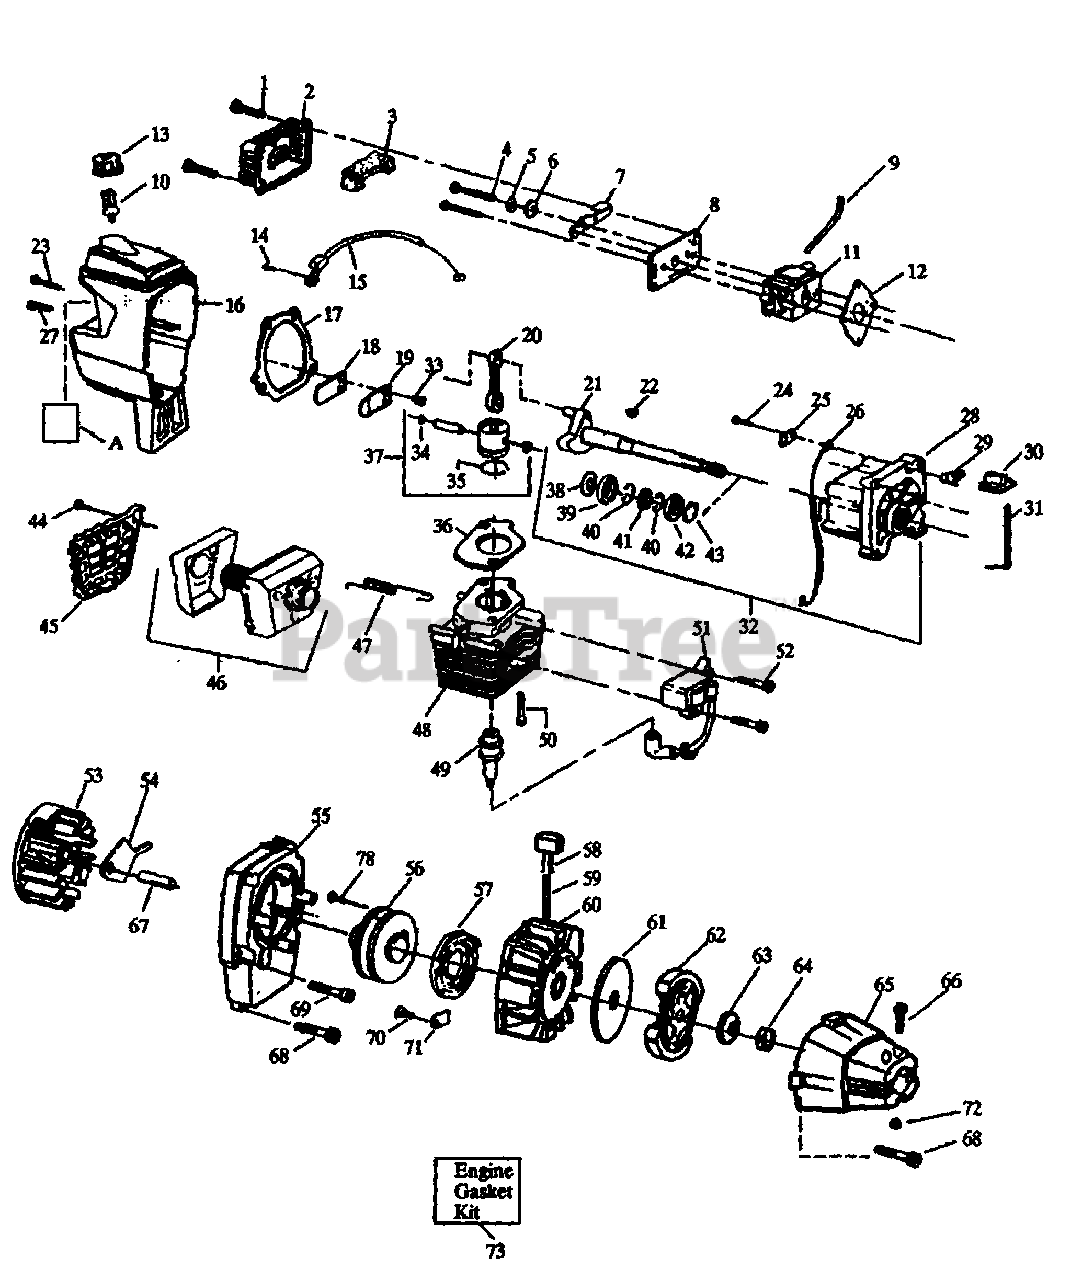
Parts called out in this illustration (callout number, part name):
2	Air Filter Cover
3	Air Filter
5	Spacer
6	Wave Washer
7	Choke Shutter
8	Air Filter Plate
9	Fuel Line 10t
10	Fuel Pick-up Ass'y.
11	Carburetor (WA-199)
12	Carburetor Gasket
13	Fuel Cap Ass'y.
15	Throttle Cable Ass'y.
16	Shroud & Tank Ass'y
17	Crankcase/Shroud Gasket
20	Connecting Rod Ass'y
21	Crankshaft Ass'y.
22	Flywheel Key
25	Kill Switch Insulator
28	Crankcase Ass'y.
29	Kill Switch Ramp
30	Kill Switch Button
31	Kill Switch Spring
32	Crankcase & Crankshaft Ass'y (#21, 28, 38 & 43)
33	Screw
34	piston Pin Retainer
35	Piston Ring
36	Cylinder Gasket
37	Piston Kit
39	Inner Bearing
40	Retaining Ring
41	Crankshaft Seal
42	Outer Bearing
43	Crankshaft Retaining Ring
45	Muffler Guard
46	Muffler Kit
47	Muffler Attachment Spring
48	Cylinder
49	Spark Plug
51	Ignition Module Kit
52	Screw
53	Flywheel Ass'y
54	Flywheel Counterweight
55	Fan Housing
56	Starter Pulley
57	Starter Spring
58	Starter Handle
60	Pulley Housing Ass'y.
61	Clutch Washer
65	Clutch Housing
73	Engine Gasket Kit
78	Screw
A	Instruction Decal
